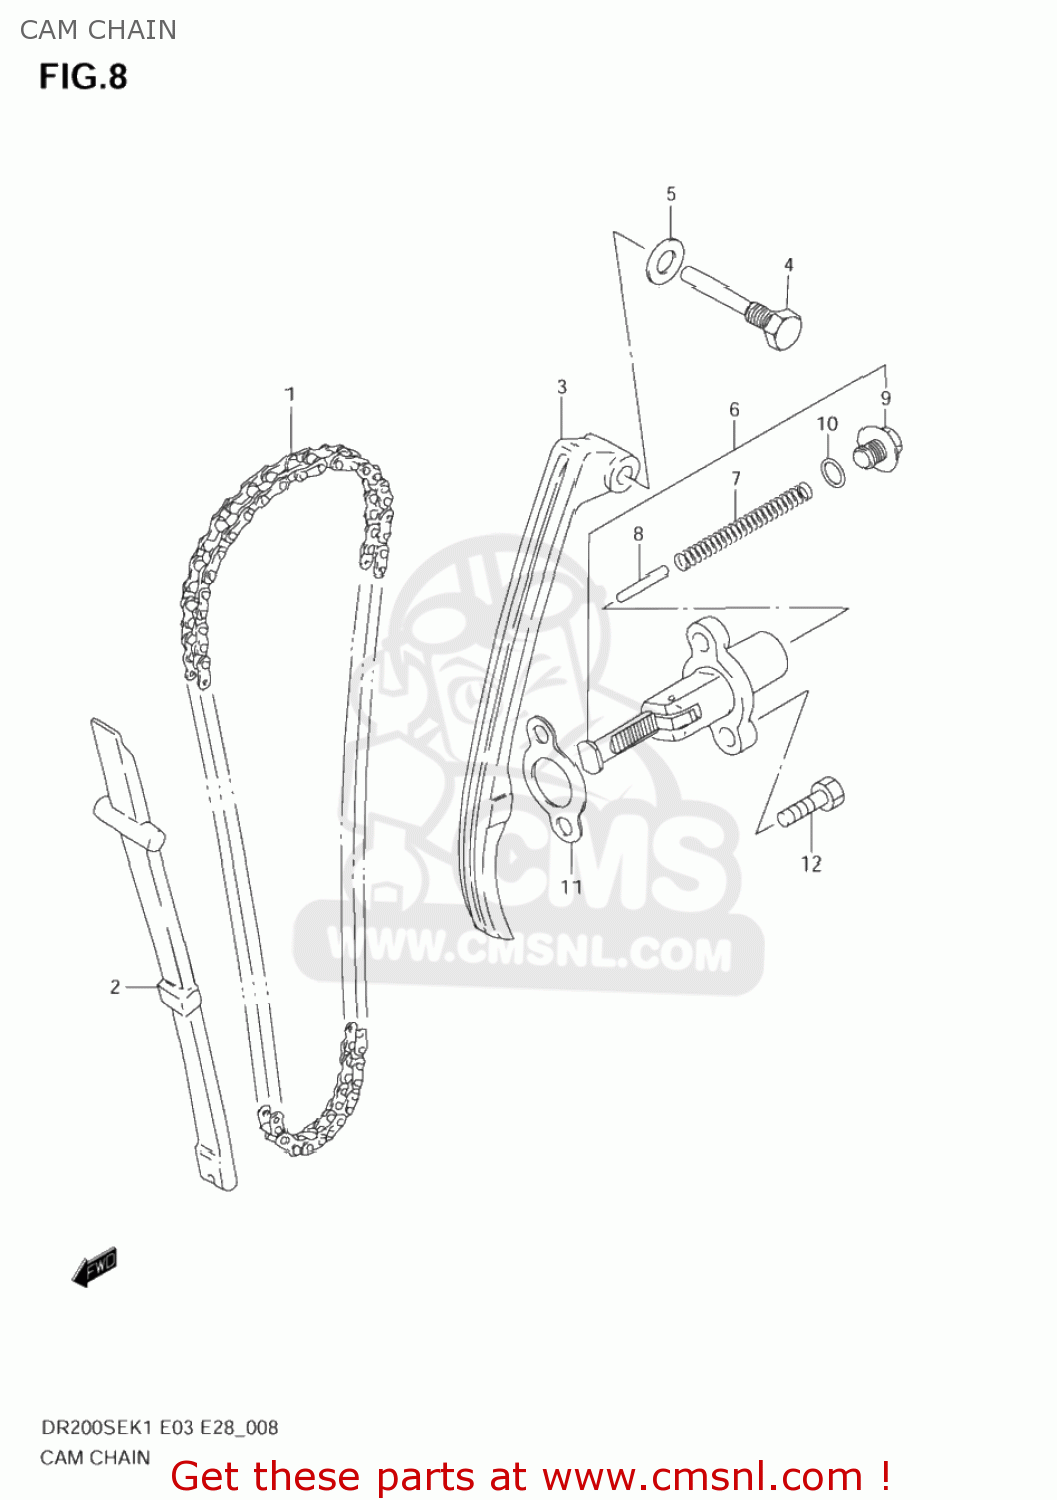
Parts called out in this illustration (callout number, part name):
1	CHAIN,CAMSHAFT DRIVE 102L
2	GUIDE,CAM CHAIN
3	TENSIONER,CAM CHAIN
4	BOLT,CAM CHAIN TENSIONER
5	GASKET(8.2X14X1) (NAS)
6	ADJUSTER ASSY,TENSIONER
7	SPRING
8	BAR
9	PLUG
10	O RING
11	GASKET,TENSIONER ADJUSTER (NAS)
12	BOLT
